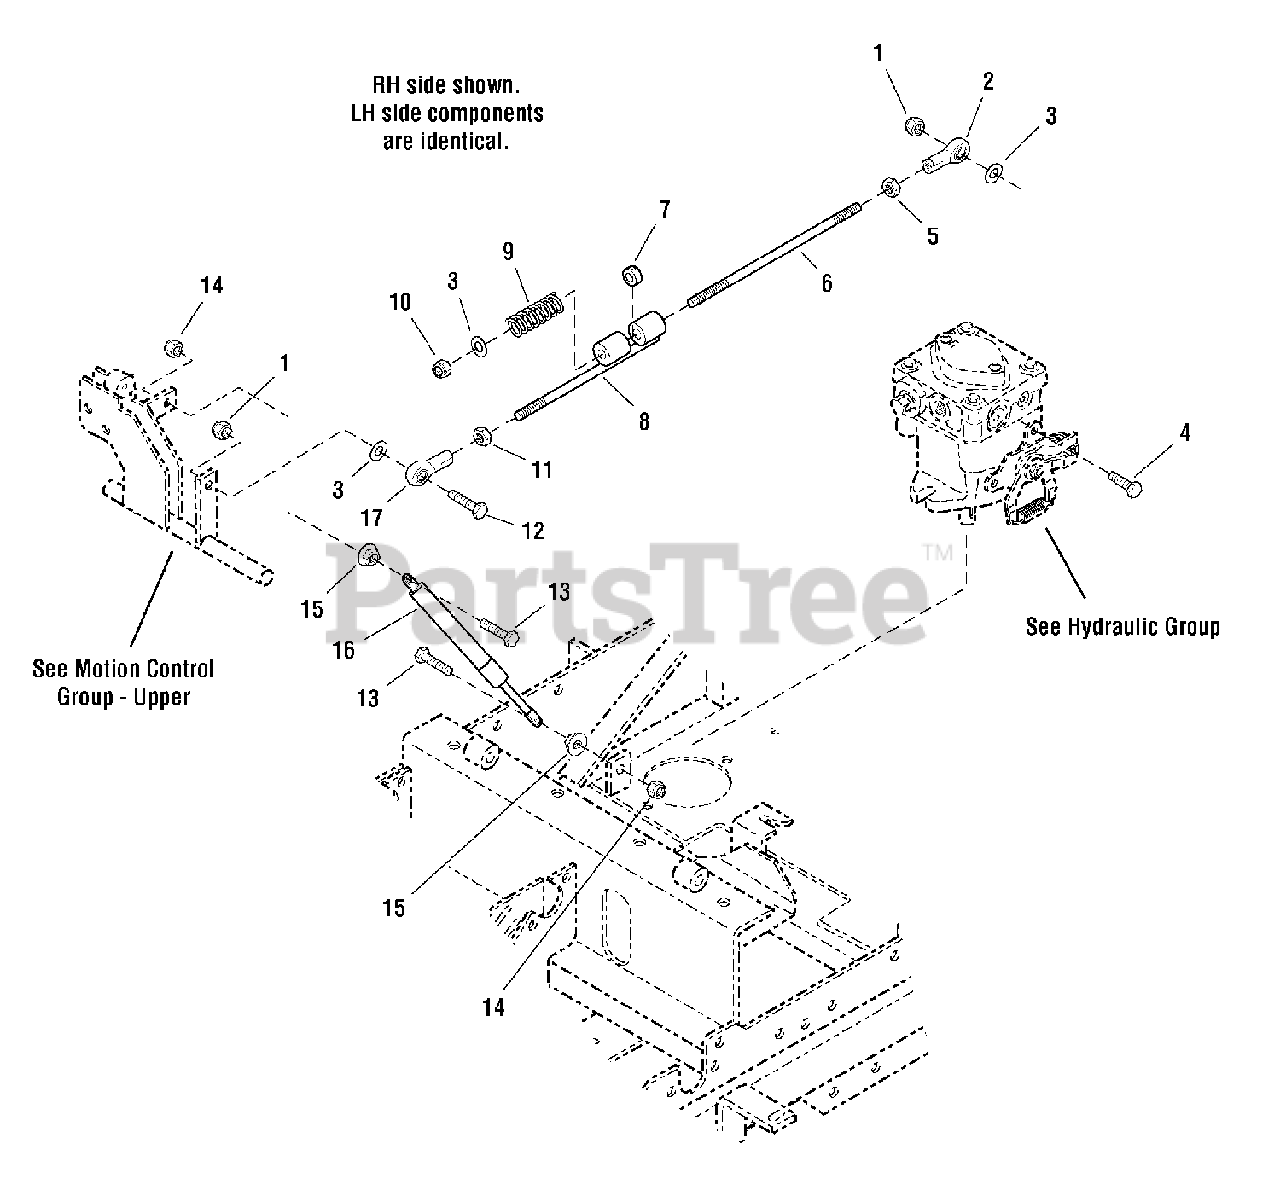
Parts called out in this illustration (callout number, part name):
1	NUT, HEX NYLON LOCK, 5/16-18
2	BALL JOINT 5/16-24 LH FEMALE STAMPED STL
3	WASHER, SAE, 5/16
4	CAPSCREW, HEX HEAD, 5/16-18 X 1-1/8
5	NUT, HEX, 5/16-24, LH
6	ROD, 5/16 X 8.38, LH-RH, CZ
7	COLLAR, SET, 5/16
8	SLIDER ROD ASSEMBLY
9	SPRING
10	NUT, HEX NYLON LOCK, 5/16-24
11	NUT, HEX, 5/16-24
12	CAPSCREW, HEX HEAD, 5/16-18 X 1-1/4
13	CAPSCREW, HEX HEAD, M8-1.25 X 35MM
14	NUT, HEX NYLON LOCK, M8-1.25
15	NUT, HEX SERRATED FLANGE, M8-1.25
16	DAMPENER
17	BALL JOINT 5/16-24 RH FEMALE STAMPED STL
